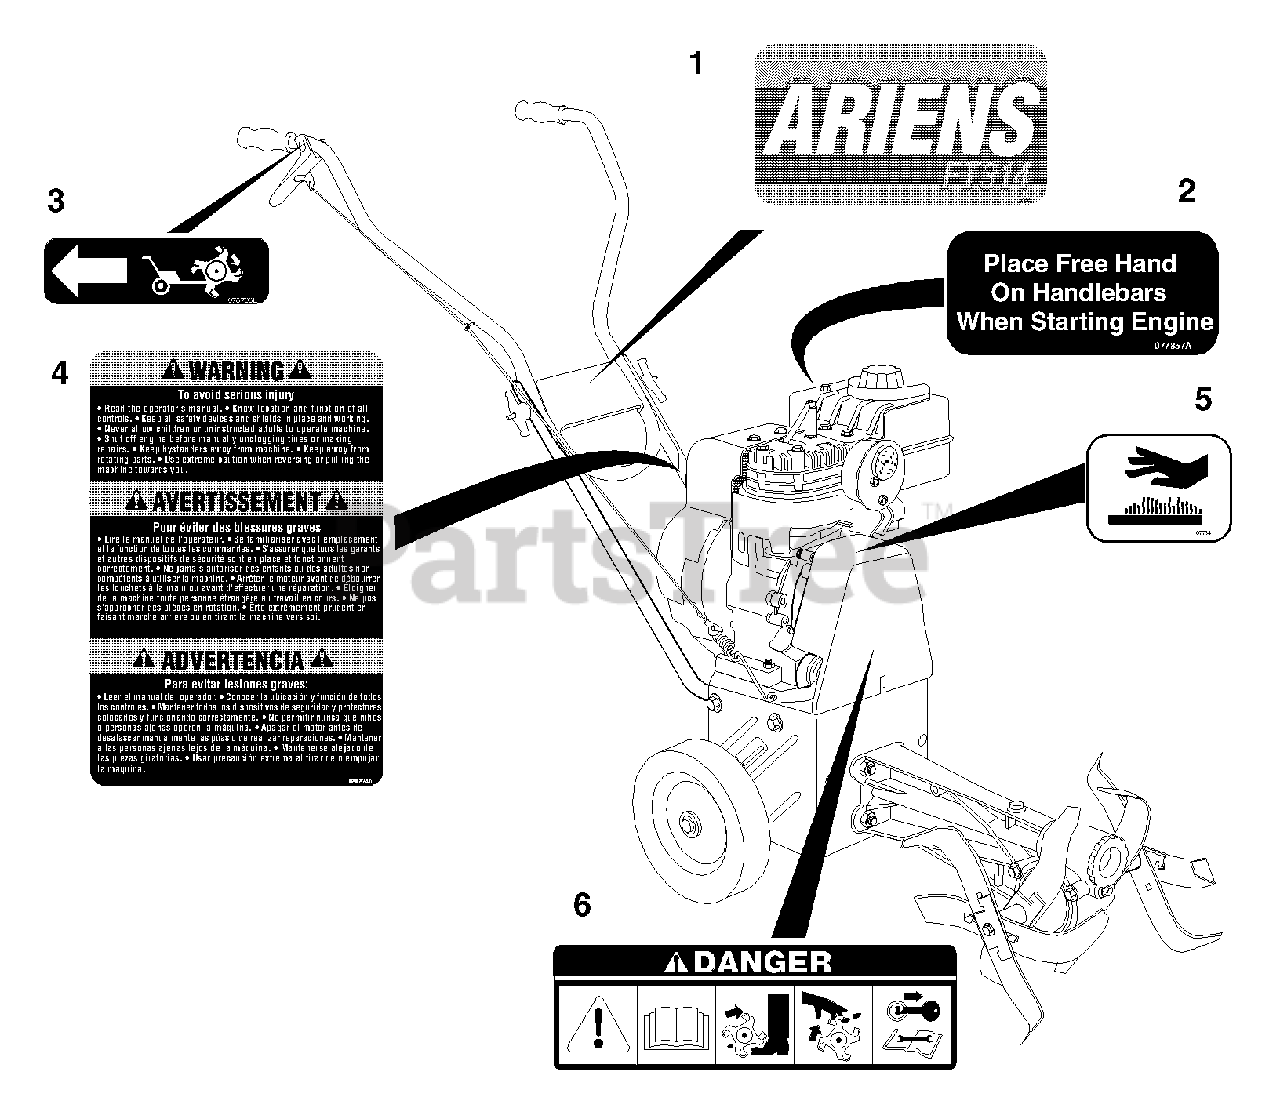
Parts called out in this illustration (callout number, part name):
1	DECAL, FT314 DASH
2	DECAL-PLACE FREE HAND
3	DECAL-FORWARD
4	DECAL, WARNING
5	DECAL, HOT SURFACE
6	DECAL, DANGER ROTATING TINES
